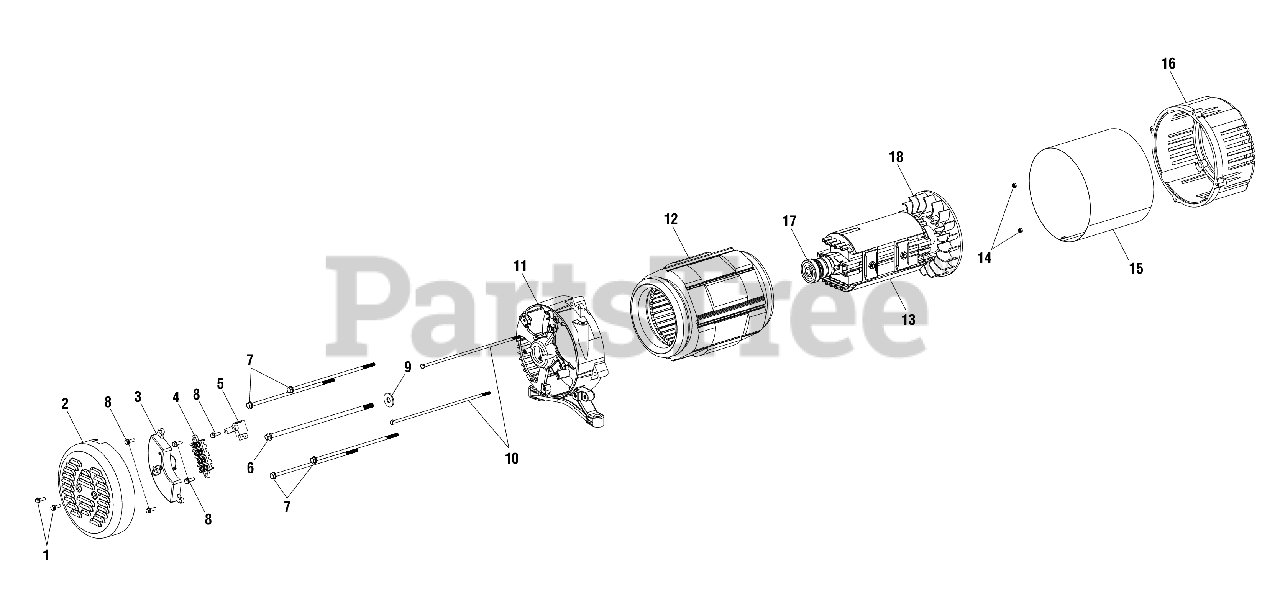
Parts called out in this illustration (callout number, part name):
1	Bolt (M5 x 12 mm, Hex Flange Hd.)
2	Brush Cover
3	Automatic Voltage Regulator (5000 Watt)
4	Terminal Block
5	Brush Assembly 190 mm
6	Bolt (5/16-24 x 235 mm, Hex Washer Hd.)
7	Bolt (M5 x 170 mm, Hex Washer Hd.)
8	Bolt (M5 x 16 mm, Hex Flange Hd.)
9	Washer (ID10.5 x OD25 x 2t)
10	Bolt (M5 x 170 mm, Hex Washer Hd.)
11	Bearing Housing'
12	STATOR ASSY RD906814 SHENFA
13	ROTOR ASSY RD906814 SHENFA
14	Hex Nut (M5)
15	Generator Head Cover
16	Generator Head Cover
17	Ball Bearing (190 mm)
18	Fan (190 mm)
